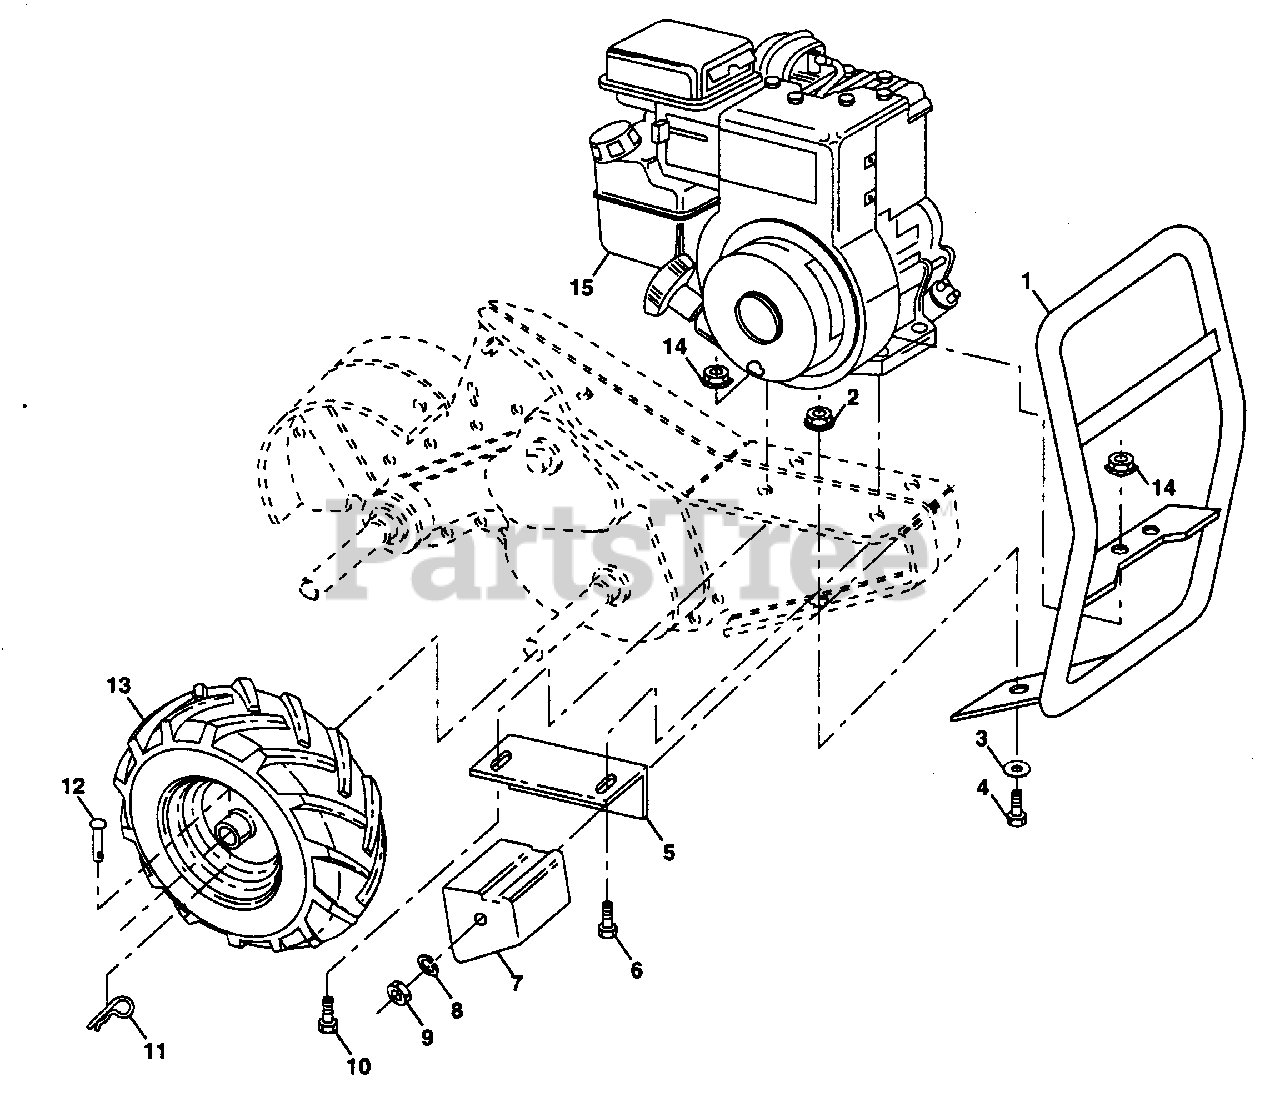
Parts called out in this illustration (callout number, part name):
1	Bumper (AYP part number)
2	Locknut, Hex, Flange 5/16-18 (AYP part number)
3	Washer 11/32 x 11/16 x 16 Ga. (AYP part number)
4	Bolt, Hex 5/16-18 x 3/4 (AYP part number)
5	Bracket, Reinforcement (AYP part number)
6	Bolt, Hex 5/16-18 x 2 (AYP part number)
7	Counter Weight, R.H. (AYP part number)
8	Washer, Lock 3/8 (AYP part number)
9	Nut, Hex 3/8-16 (AYP part number)
10	Bolt, Hex 5/16-18 x 1-1/2 (AYP part number)
11	Clip, Hairpin (AYP part number)
12	Rivet, Drilled (AYP part number)
13	Tire (AYP part number)
14	Nut, Keps 5/16-18 (AYP part number)
